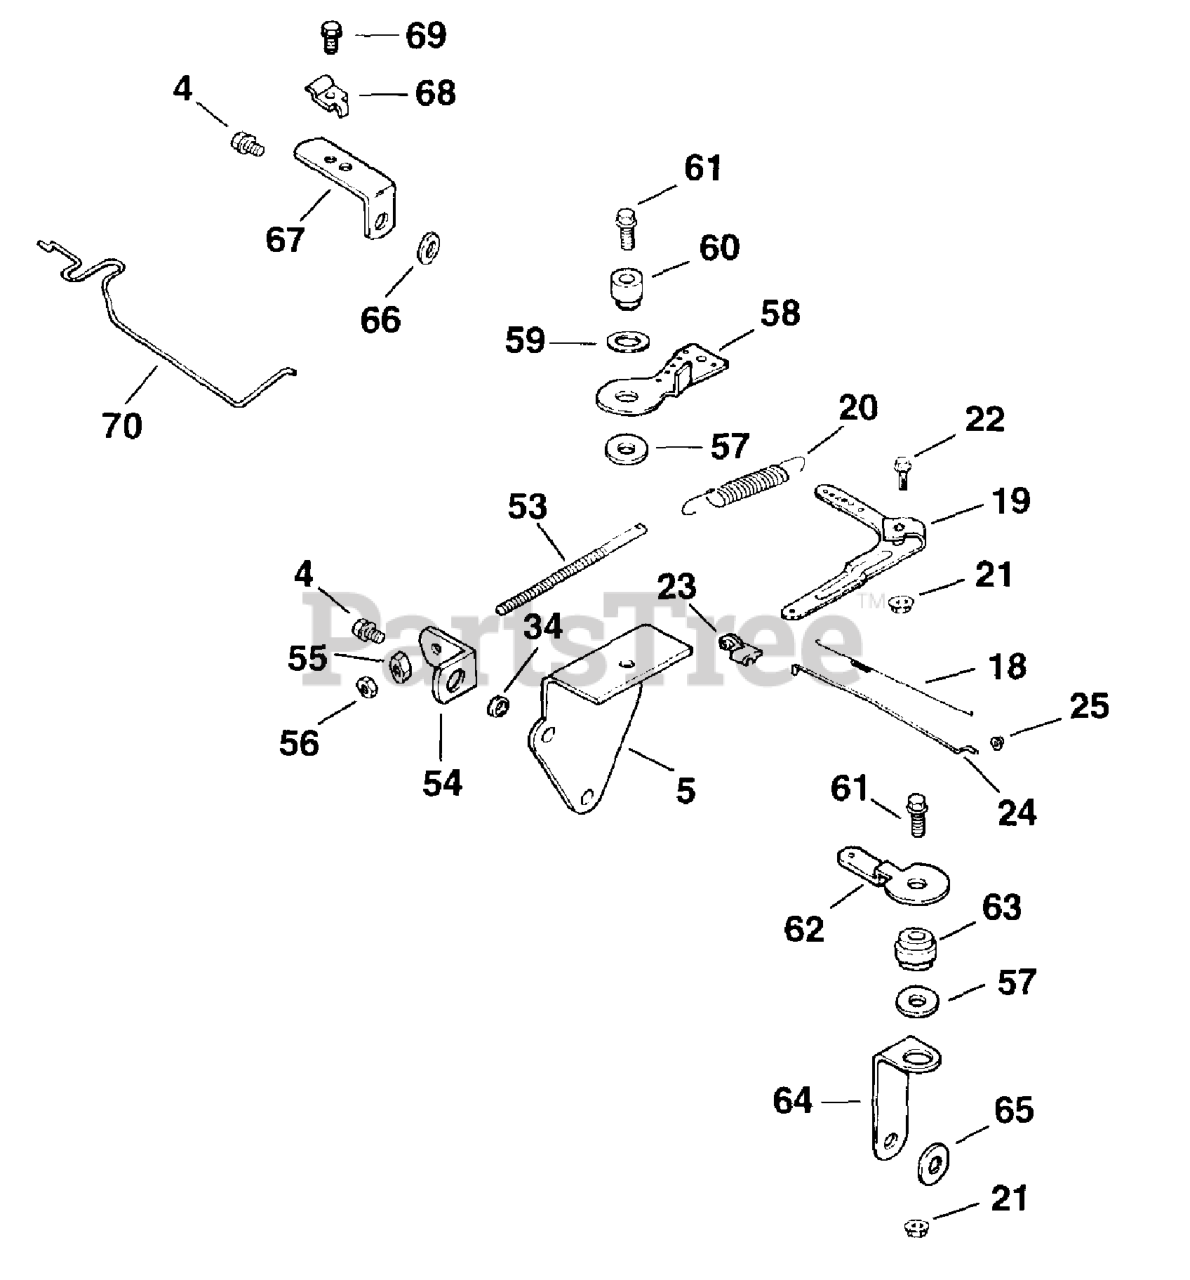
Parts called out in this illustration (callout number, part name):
4	SCREW - USE M-645016
18	SPRING, LINKAGE
19	LEVER, GOVERNOR - DISCONTINUED
20	SPRING, GOVERNOR (CLEAR)
21	NUT - USE M-641060
22	Screw, hex. cap M6x1.0x25
23	BUSHING, THROTTLE LINKAGE
24	LINKAGE, THROTTLE
25	BUSHING, LINKAGE RETAINING
53	ROD, SPEED CONTROL
55	NUT, ADJUSTING
56	NUT, MACH SCREW #10-32 GRD 2 USE 25 100 18-S
59	WASHER, SPRING 11/32"
61	SCREW - USE M-645025
63	SPACER
64	STRAP, LIFTING
65	WASHER,INT EXT TOOTH LOCK 5/16"
66	WASHER,INT EXT TOOTH LOCK 1/4"
69	SCREW, WSH HD TAP #10-24X13/32" USE 25 086 109-S
